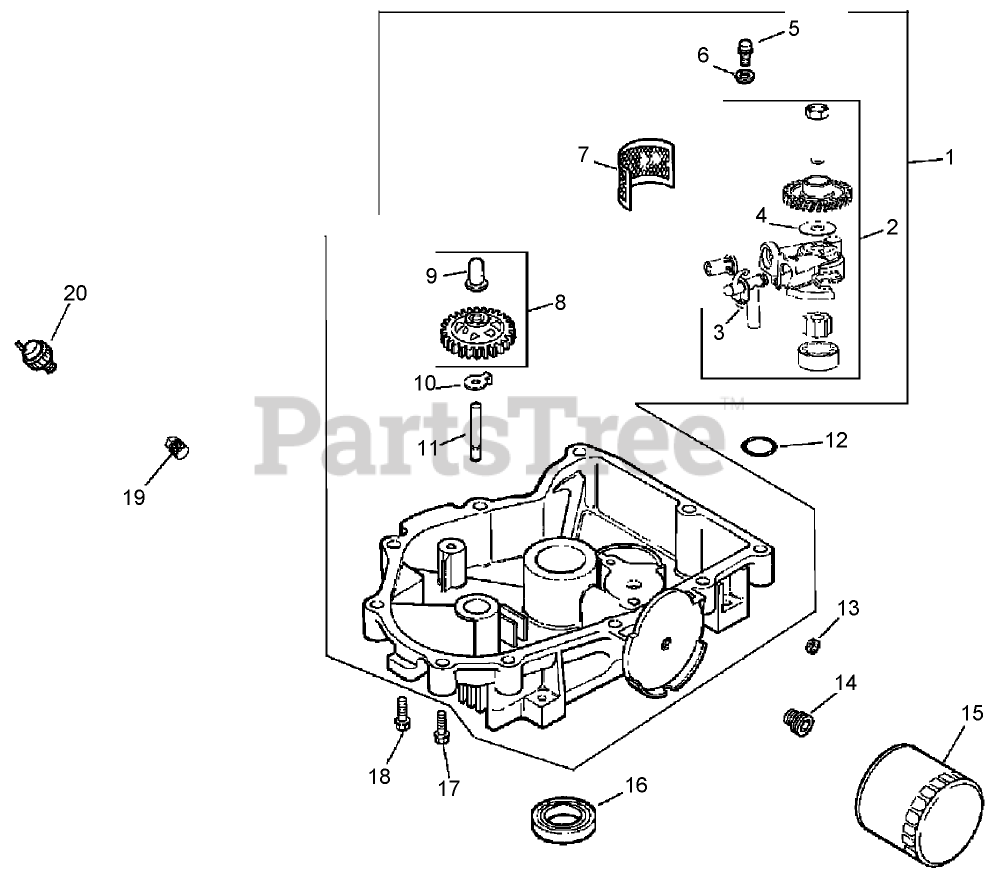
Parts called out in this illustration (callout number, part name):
1	Pan assembly, oil (Incl. Ref. # 2-11)
2	Pump assembly, oil (Incl. Ref. # 3,4)
3	Tube-pickup, oil
4	O-RING
5	SCREW-FLANGE, THREAD FORMING (M6X1.0X25)
6	WASHER-FLAT (6 MM)
7	Screen-oil
8	Kit, governor gear w/pin (Incl. Ref. # 9)
9	PIN-REGULATING, GOVERNOR
10	TAB-LOCKING
11	SHAFT-GEAR, GOVERNOR
12	O-Ring
13	Plug-pipe, HH (3/8)
14	Nipple-Filter, Oil
15	FILTER-OIL
16	SEAL-OIL (P-T-O END)
17	SCREW-FLANGE (M8X1.25X45)
18	Screw-HF (M8x1.25x45)
19	PLUG-PIPE, SQ HD (3/8)
20	SWITCH-PRESSURE, OIL
